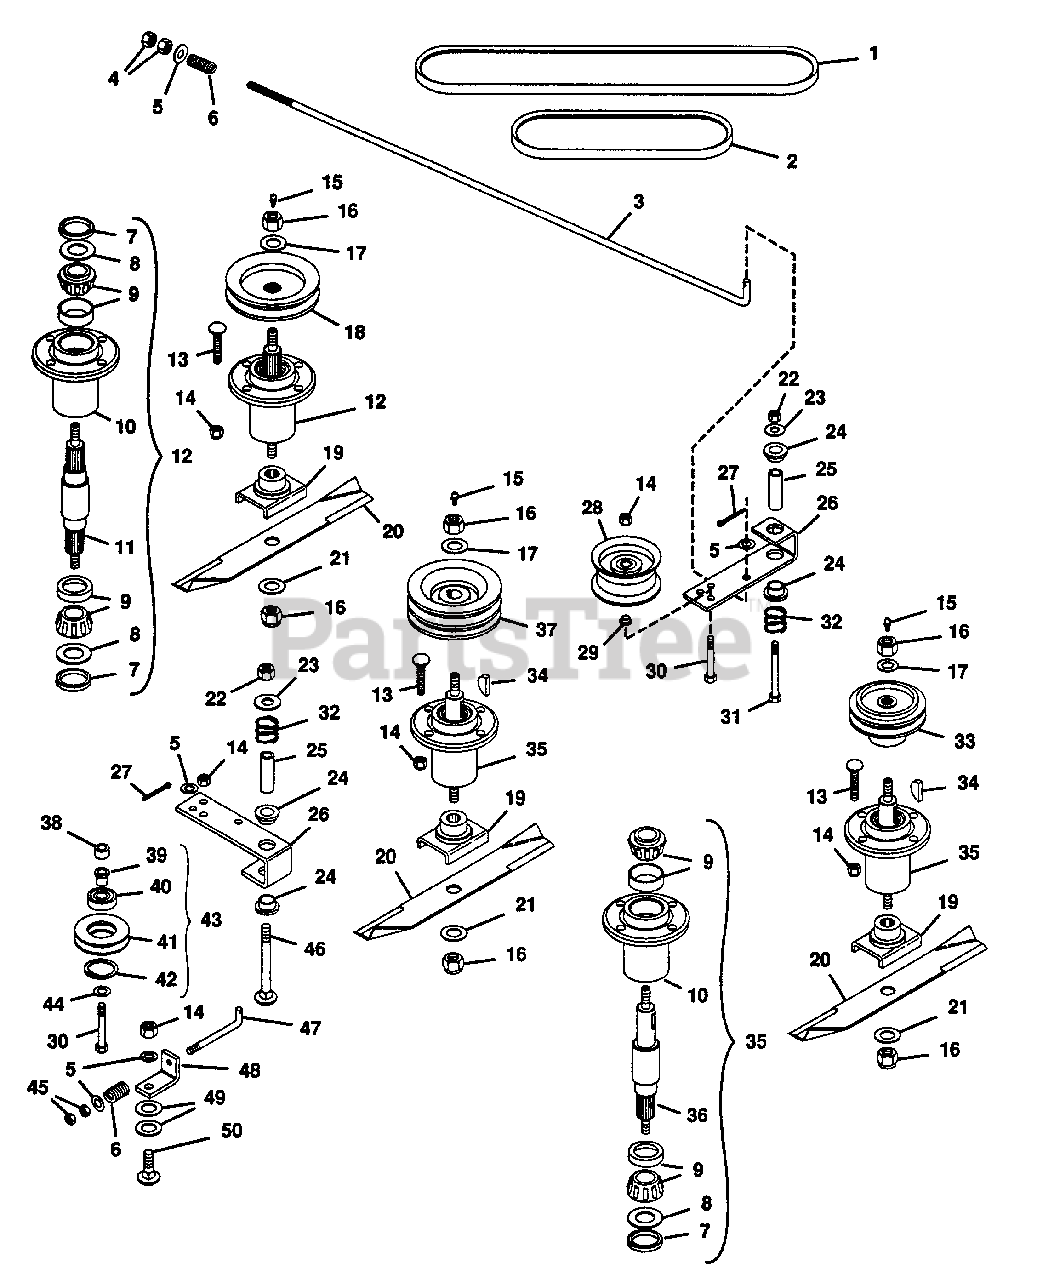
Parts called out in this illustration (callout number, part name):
1	Belt, V
2	Belt, V
3	Rod, Idler
4	Nut, Hex 3/8-24
5	Washer, Flat .406x.812x.065
6	Spring, Comp. 1x.78x338 Lb/N
7	Seal, Steel(in 34605)
7	Seal, Steel(in 21306)
8	Washer, Flat .975x1.970x.030(in 34605)
8	Washer, Flat .975x1.970x.030(in 21306)
9	Assembly, Bearing
10	Housing, Bearing
11	Shaft, Spindle
12	Assembly, Spindle
13	Bolt, 3/8-16x1.375 Rd Hd Sq Nk
14	Nut, Lock 3/8-16
15	Fitting, Lube 1/8
16	Nut, Lock 5/8-11
17	Washer, Flat .687x1.312x.122
18	Pulley
19	Weldment, Blade Cradle
20	Blade, 50 Inch mower
21	Washer, Flat .656x1.312x.095
22	Nut, Lock 1/2-13
23	Washer, Flat .531x1.250x.100
24	Bush., Flg. .764x1.47x.560 Ny.
25	Bush., St. .560x.750x2.44 Stl.
26	Arm, Idler Pivot
27	Pin, Cotter .09x1.00
28	Pulley, Idler
29	Bush., Flg. .406x.880x.270 Br.
30	Bolt, Hex 3/8-16x2.25
31	Bolt, Hex 1/2-13x3.50
32	Spring, Comp. 1x.80x36 Lb/N
33	Sheave
34	Key, Woodruff .250x1 Hard #15
35	Assembly, Spindle
36	Shaft, Spindle
37	Sheave, Mower Spindle
38	Bush., St. .406x.625x.480 Stl.
39	Bush., Flg. .391x1.00x.760 Stl.
40	Bearing, Ball
41	Sheave, Idler
42	Ring, Retaining
43	Assembly, Idler Sheave
44	Washer, Flat .375x1.125x.065
45	Nut, Hex 3/8-16
46	Bolt, 1/2-13x3.50 Rd Hd Sq Nk
47	Rod, Idler
48	Bracket, Belt Tensioner
49	Washer, Flat .531x1.062x.095
50	Bolt, 3/8-16x1.25 Rd Hd Sq Nk
